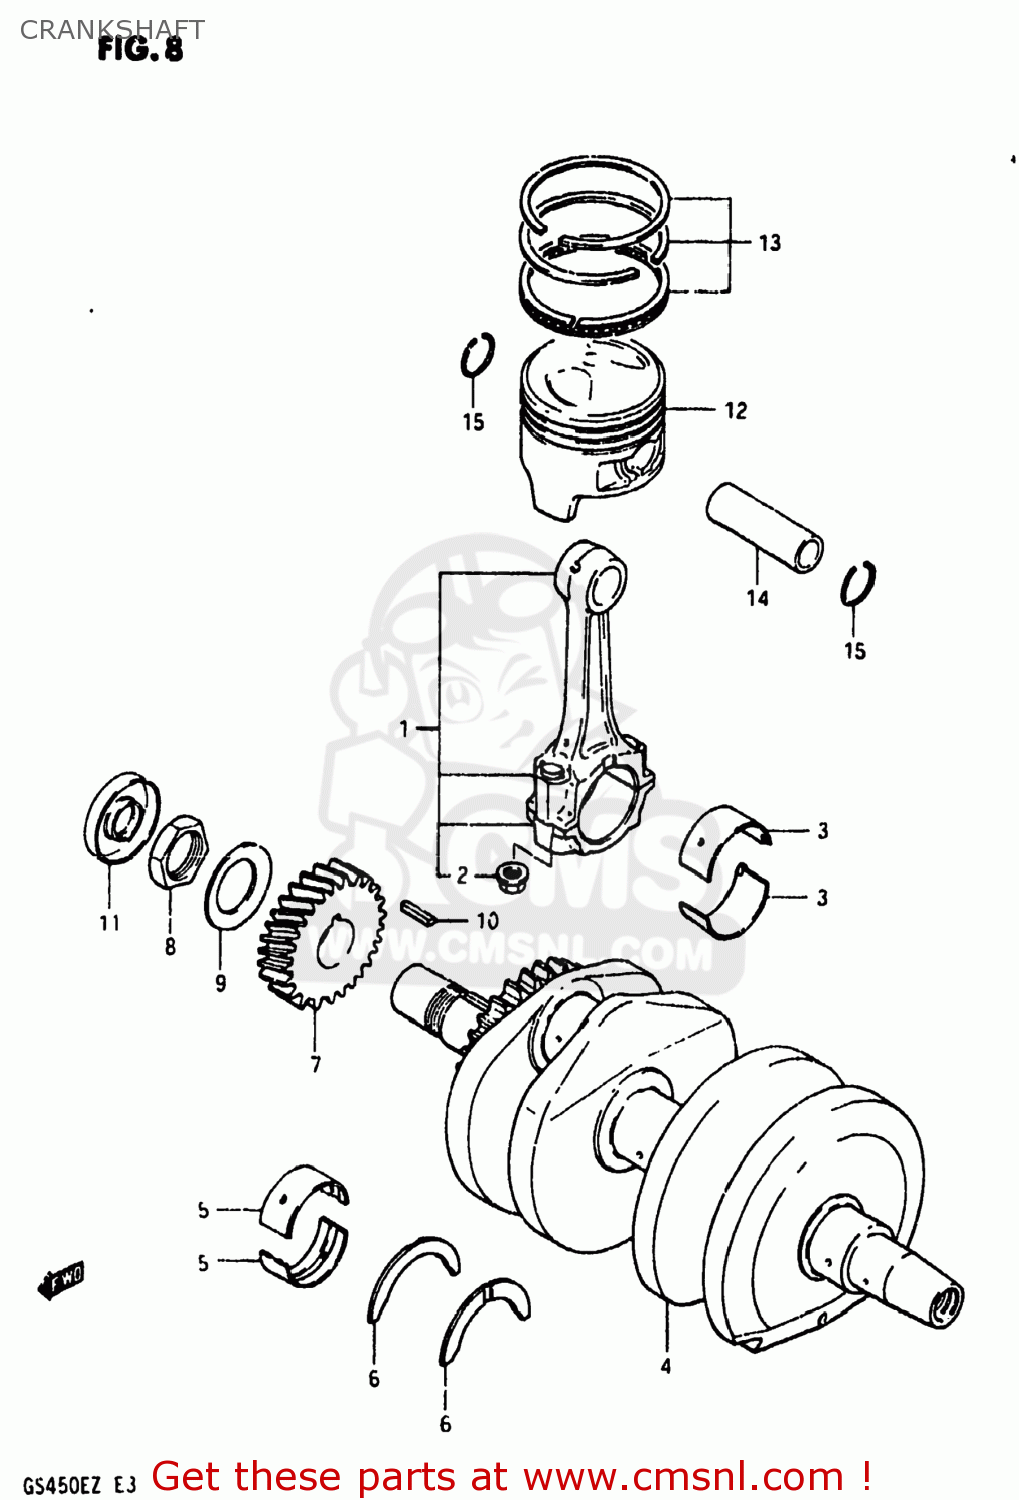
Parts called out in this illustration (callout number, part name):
1	ROD ASSEMBLY,CONNECTING
2	NUT
3	BEARING,CRANK PIN
4	CRANKSHAFT
5	METAL CRANKSHAFT
6	PLATE,CRANK THRUST
7	GEAR,PRIMARY DRIVE NO.28
8	NUT
9	WASHER
10	KEY
11	OIL SEAL
12	PISTON
13	RING SET,PISTON
14	PIN,PISTON (18MM)
15	CIRCLIP
